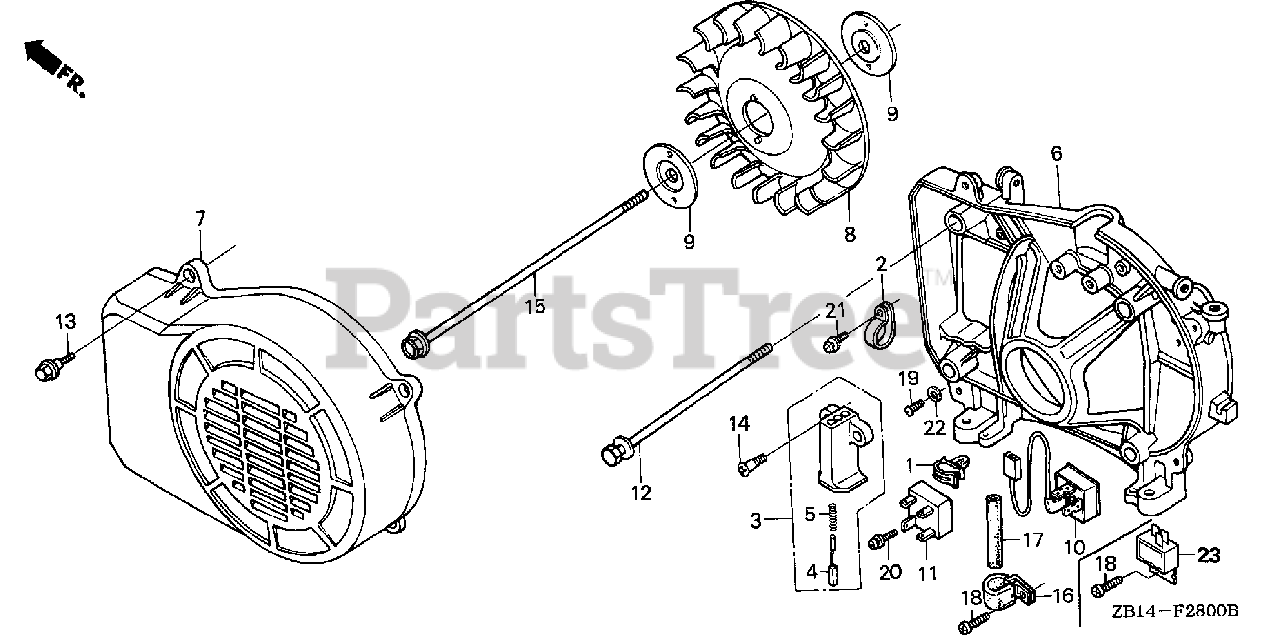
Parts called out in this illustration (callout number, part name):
2	CLAMP C, CABLE
3	HOLDER ASSY., BRUSH
5	SPRING, BRUSH
6	HOUSING, RR.
7	COVER, GENERATOR END
8	FAN, COOLING
9	PLATE, FAN
10	DIODE, D.C.
12	BOLT, FLANGE (6X137)
13	BOLT, GENERATOR END COVER
14	BOLT, STATOR COVER SETTING
15	BOLT, FLANGE (8X175)
16	CLIP, WIRE
17	TUBE, WIRE
18	SCREW, PAN (5X8)
19	SCREW, PAN (5X12)
20	SCREW-WASHER (4X18)
21	SCREW-WASHER (5X12)
22	WASHER, SPRING (5MM)
